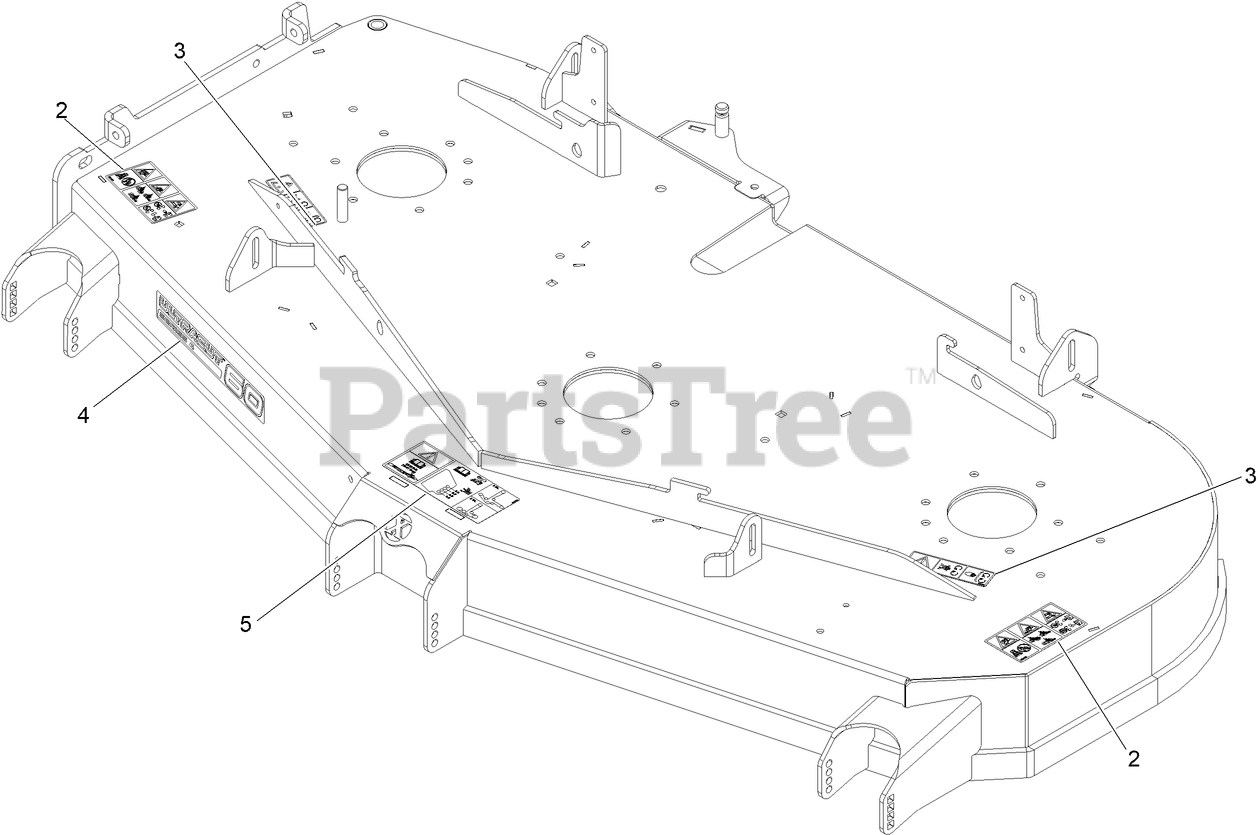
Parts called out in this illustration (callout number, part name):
2	DECAL-DANGER THROWN OBJECTS
3	DECAL-COVER, MISSING
4	DECAL, 604
5	Decal-Anti-Scalp-Belt Routing
